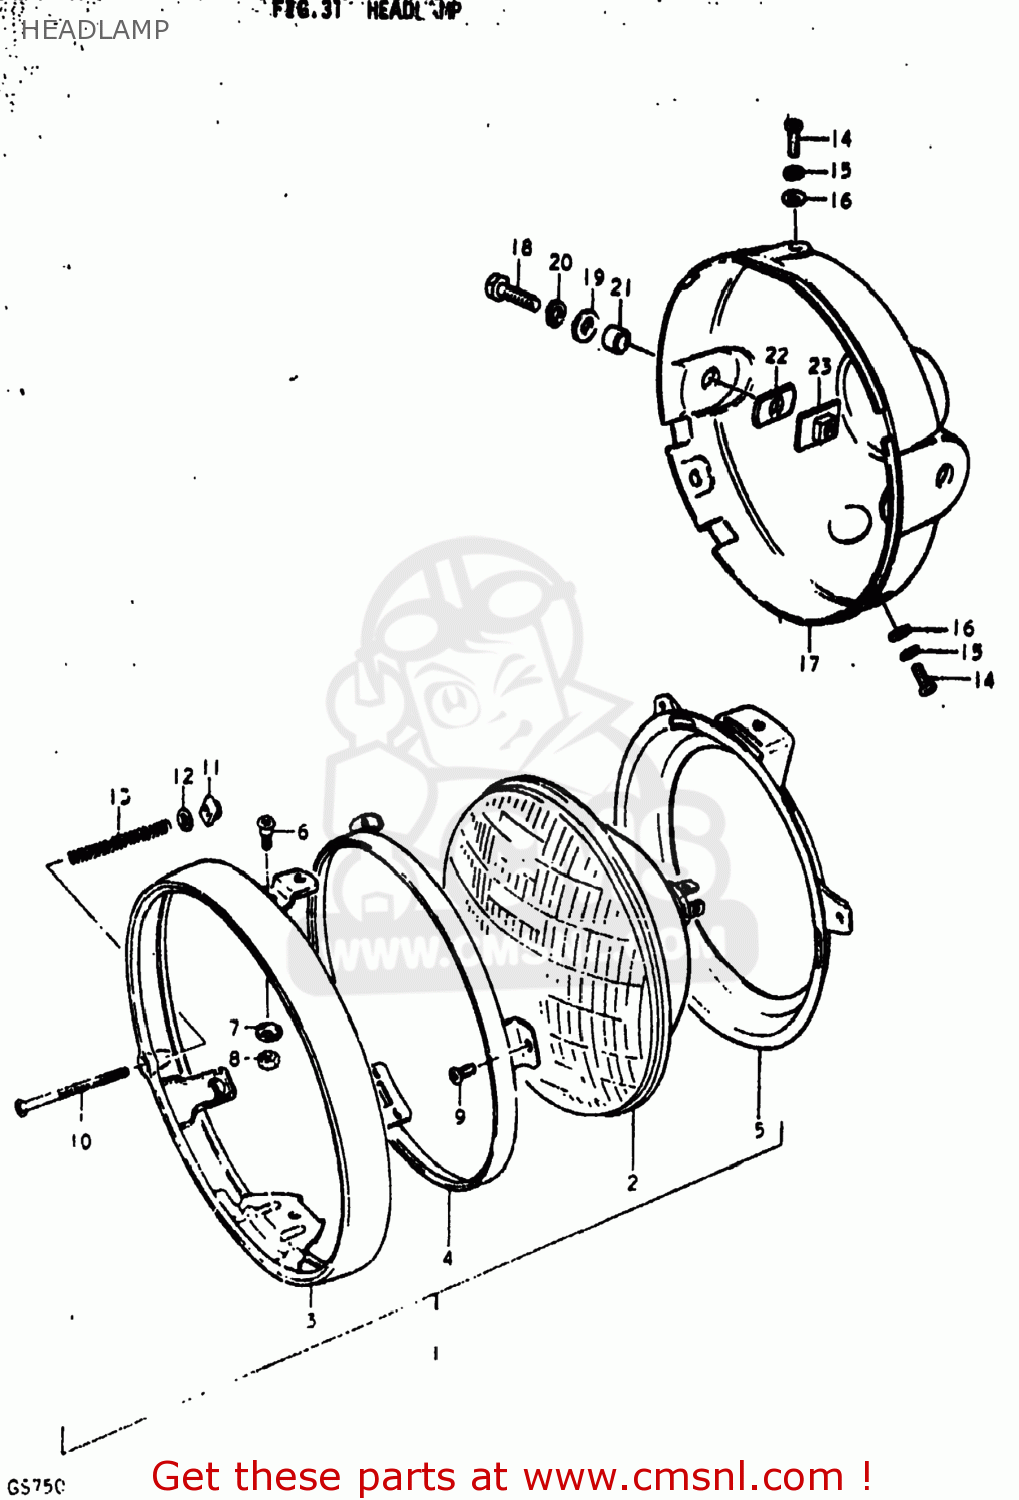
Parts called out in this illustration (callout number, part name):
1	HEADLAMP ASSEMBLY
2	LAMP UNIT
3	RIM
4	RETAINER
5	RING,HEADLAMP UNIT
6	SCREW
7	SPACER
8	NUT,ADJUSTING
9	SCREW
10	SCREW,HEADLAMP ADJUST
11	NUT
12	WASHER
13	SPRING,HEADLAMP ADJUST
14	SCREW
15	WASHER,LOCK
16	WASHER
17	HOUSING,HEADLAMP(BLACK)
18	BOLT
19	WASHER 8MM
20	LOCK WASHER
21	SPACER (8.8X12X7)
22	CUSHION
23	PLATE,HEADLAMP HOUSING
